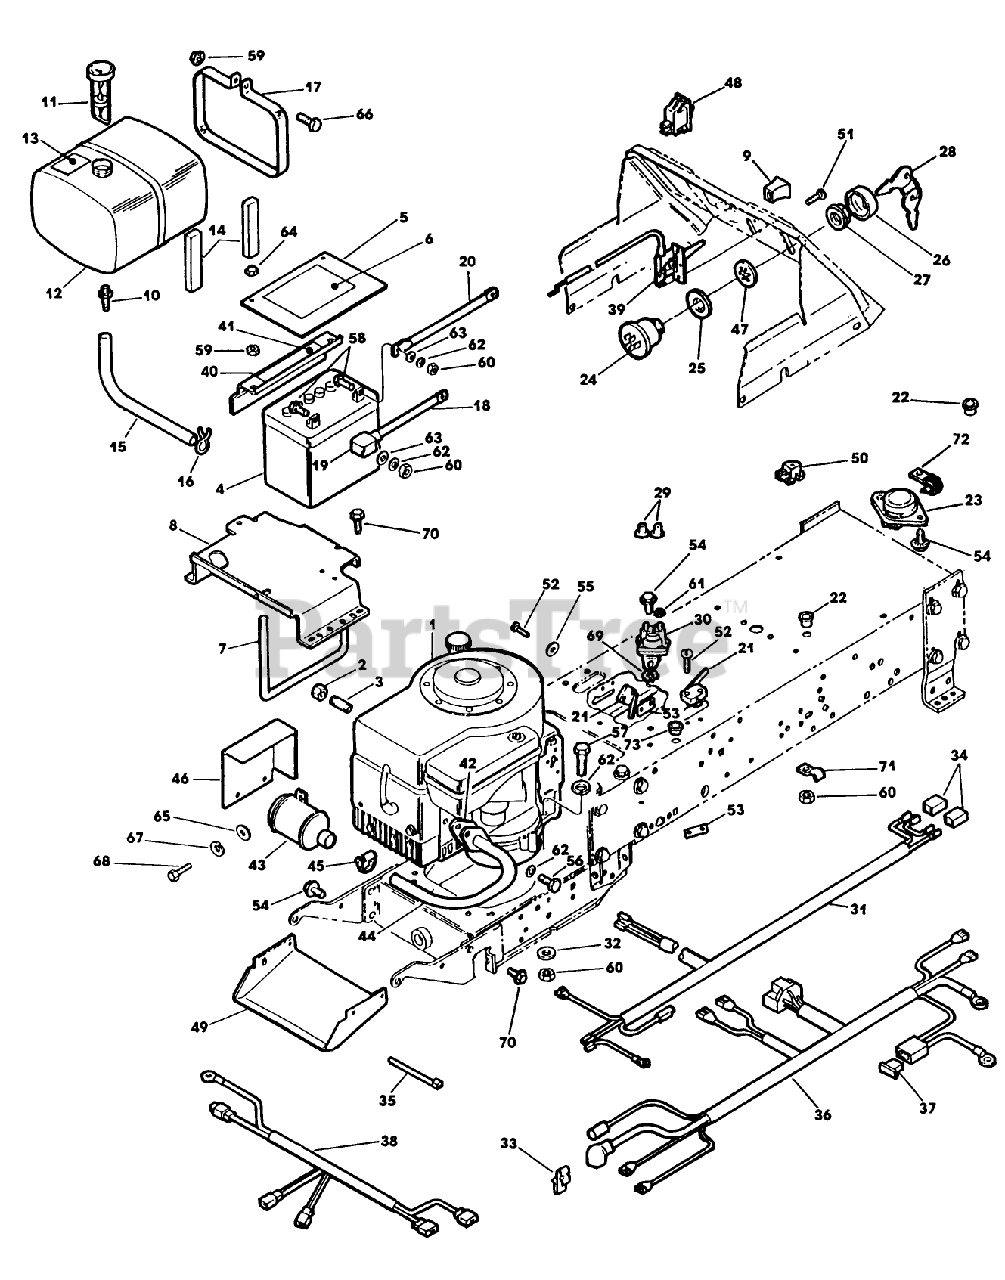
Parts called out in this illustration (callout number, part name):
5	BATT. CVR & R/B 744648
9	THROTTLE KNOB
11	FUEL CAP&GUAGE AY.
18	CABLE ASSEMBLY
23	SWITCH,SEAT
30	SOLENOID
40	HOLD DOWN & DECAL (12)
43	MUFFLER AY
48	SWITCH ASSEMBLY
58	SCREW - HEX
61	NUT-HEX
64	NUT-LOCK, CONE
